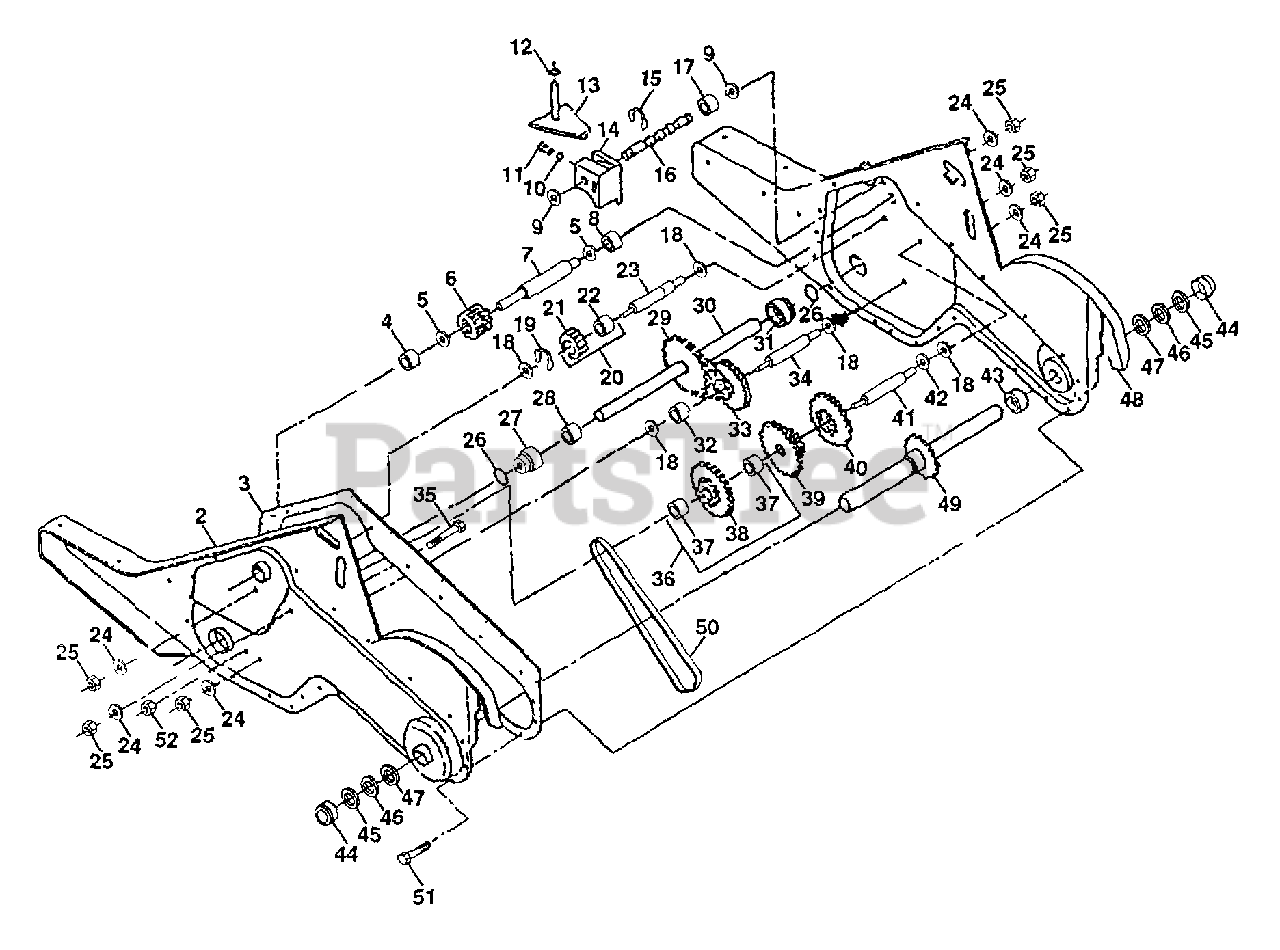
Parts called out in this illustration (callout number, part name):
3	GASKET TI
4	NEEDLE BRNG LT
5	"T, BEARING"
6	PINION-INPUT CRT
7	SHAFT-INPUT CRT
8	"TI, BEARING"
9	WASHER SEAL CRT
11	SPRING-SHIFT CRT
12	O-RING TI
13	ARM ASSY CRT
14	SHIFT FORK TI
15	KLIP RING
16	SHAFT SHIFT CRT
17	SPACER SPLIT CRT
18	WASHER
19	KLIP RING
20	GEAR ASSY CRT
21	GEAR-REV IDLR CRT
22	NEEDLE BEARING TI
23	SHAFT CRT
24	LOCKWASHER
25	NUT.ASF.HEX.7/16
26	O RING CRT
27	"CRT, BEARING"
28	BUSHING TI
29	CHAIN CRT
32	SPACER TI
33	SPRCKT 8 GEAR CRT
34	SHFT 2ND RED. CRT
35	SCRW WHIZ LOK CRT
37	BEARING
39	GEAR TI
40	GEAR TI
41	REDUCTION SHFT TI
42	BRNG RACE
44	CUP.FORMED.
45	RING SPIRAL CRT
49	TINE SHAFT
50	CHAIN.50 LINK TI
51	SCREW CRT
52	NUT.HEX.5/16-18
